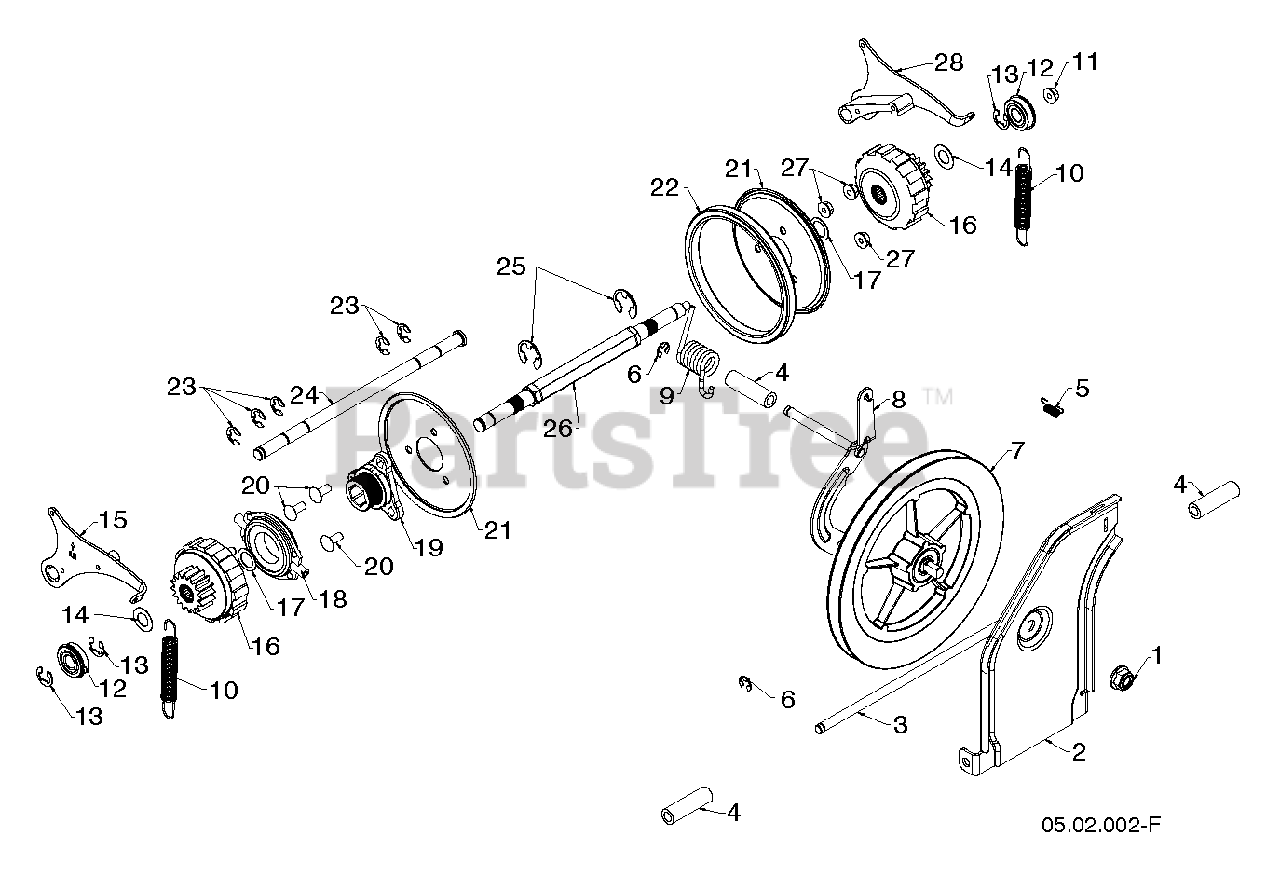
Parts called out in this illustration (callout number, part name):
1	NUT, 1/2-13 HEX FLG NYLOC ZD
2	Plate, Swing Friction Pulley 47
3	ROD.TIP.PLATE
4	SPACER YOKE, TORSION SPRING
5	SPRING LATCH
7	Friction Disc Combo Pulley
9	Drive Torsion Spring
10	PS Extension Spring
11	Flange Hex Lock Nut, 5/16-18
12	Bearing, 9/16" Id. Snr
13	Retaining Ring
14	Flat Washer, .637Id X 1.00Od X 21Ga
15	PAWL.ASM.RH.SNOW
16	Gear Assembly Planetary
17	Flat Washer, .59Id X 1.065Od X 25Ga
18	TRUNNION BEARING ASSY
19	HUB.RUBBER.WHEEL
20	BOLT.5/16-18.
21	Wheel Plate, Rubber Black
22	Ring, Rubber
23	E-Ring Clip, .500 Shaft
24	ROD ROD, PAWL ROD
26	Power Str Shaft
27	NUT.LOCK.5/16-18
28	PAWL.ASM.LH.SNOW
